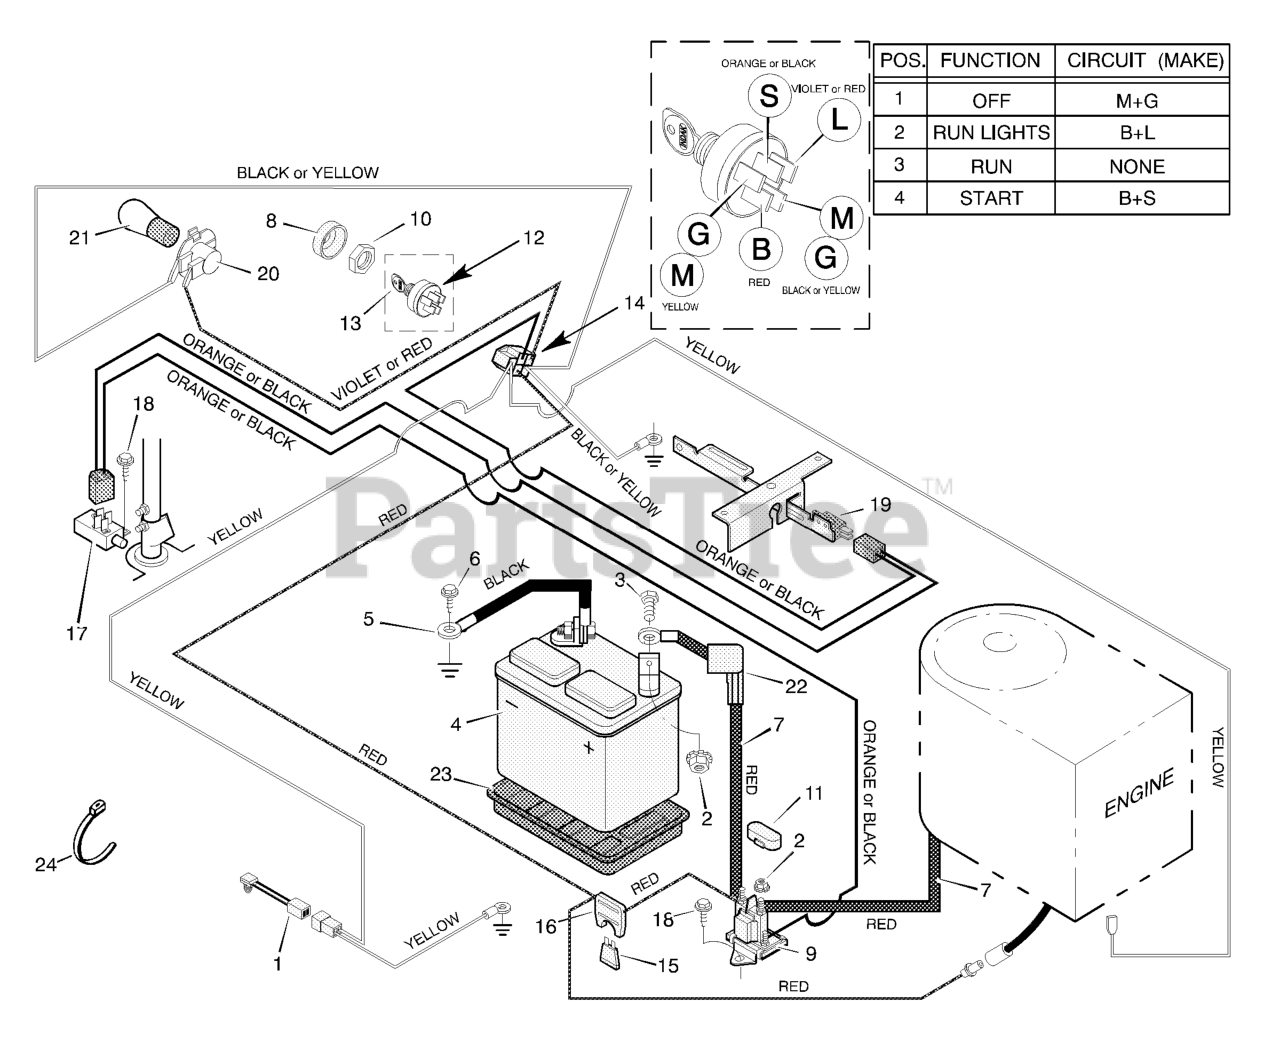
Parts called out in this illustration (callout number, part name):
1	Switch, Seat Sensor
2	Locknut
4	Battery
5	Cable, Battery Ground
7	Cable, Red Battery
8	Cap, Ignition
9	Solenoid
10	Nut, Hex
12	Switch, Ignition
13	Key, Ignition
14	Harness, Chassis Wire
16	Holder, Fuse
17	Switch, Limit
19	Switch, Limit
20	Socket, Light
21	Bulb, Light
22	Cover, Terminal
23	Tray, Battery
